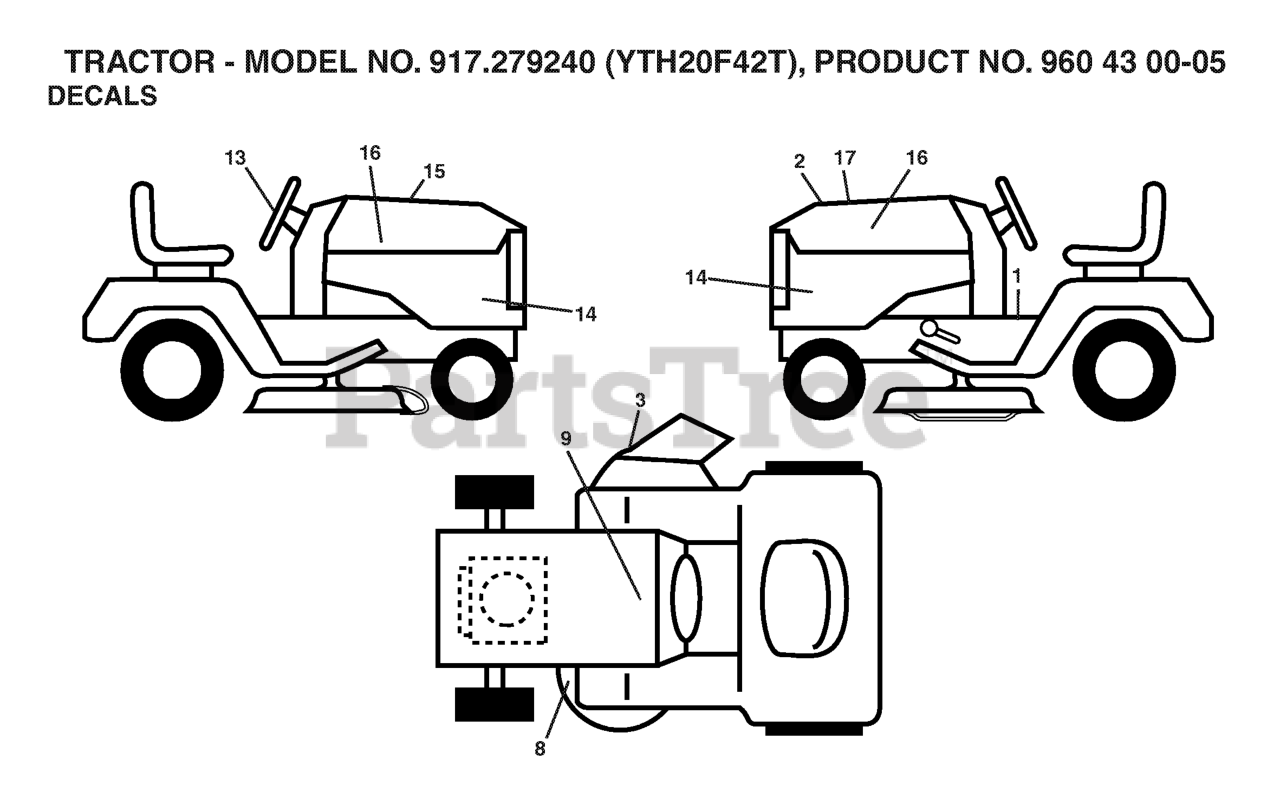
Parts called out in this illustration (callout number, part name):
2	DECAL.HOOD.TOP.INSERT.
3	DECAL.WARN.KEEP.HAND.AWAY
8	DECAL V BELT SCHEMATIC
9	DECAL BTRY SYMBOLS
13	DECAL.STEERING.HUSQ.BLUE
15	DECAL HOOD CUST. RESP.
16	DECAL.HOOD.NAMELOGO.HUSQ
